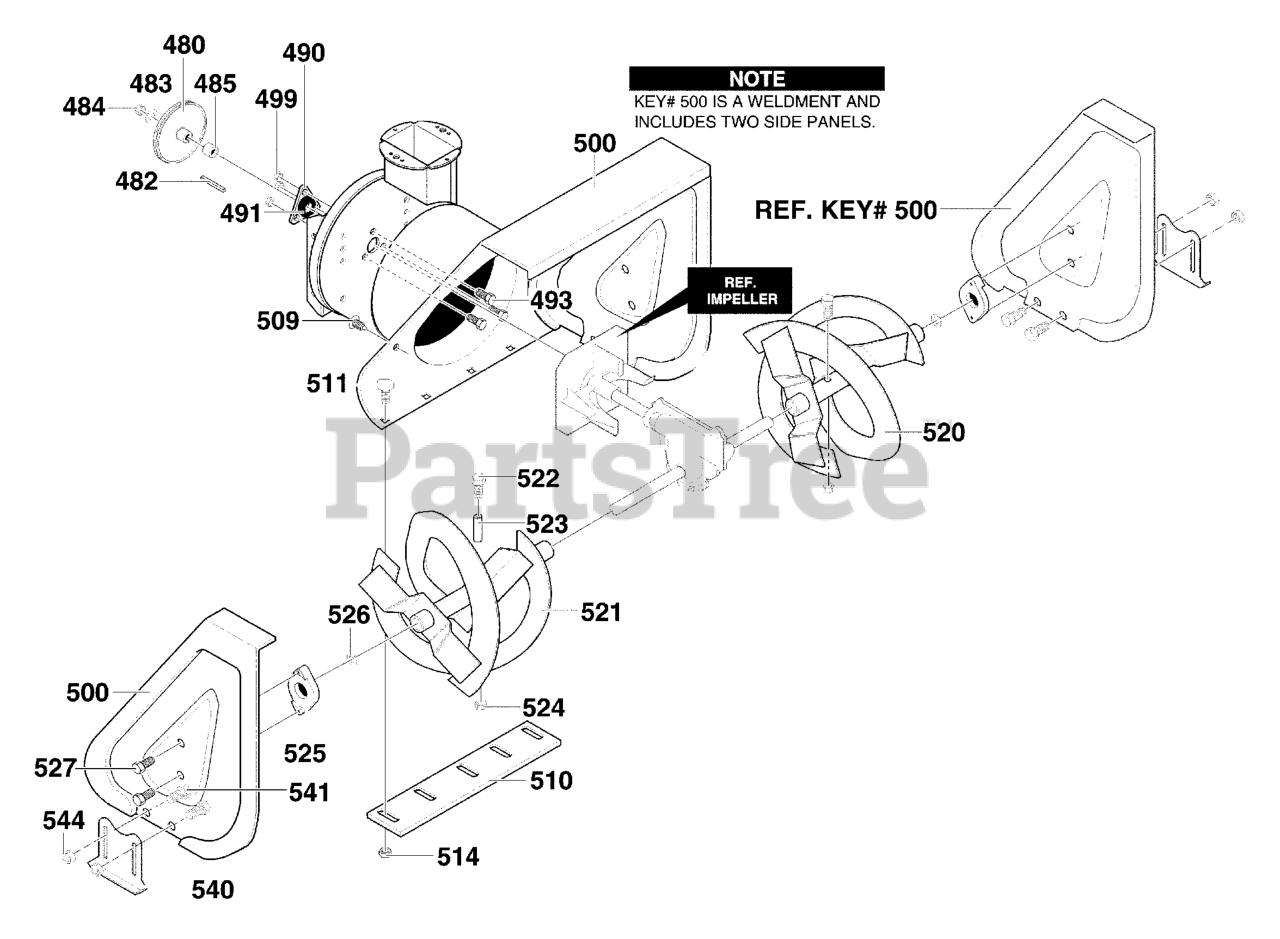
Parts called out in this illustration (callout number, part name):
482	KEY, SQUARE
483	FLATWASHER
484	NUT, 1/4-20
485	SPACER, FRICTION PULLEY
490	RETAINER, BALL BRNG
491	BEARING, BALL
493	BOLT, HEX - 0.31-18X0.50
499	NUT, 5/16-18 HEXWDFLLK
500	HOUSING, ASSY
509	PLUG, CHRISTMAS TREE
510	BLADE, SCRAPER
511	BOLT, 1/4-20X.75
520	AUGER, ASSY, LH
521	AUGER, ASSY, RH
522	SCREW, 1/4-20X1.75
523	SPACER, SLEEVE
524	NUT, 1/4-20
525	BEARING,FLANGE
527	SCREW, 5/16-18 x 0.75
540	SKID, HEIGHT ADJUST
541	BOLT, 5/16-18 X .75
544	NUT, 5/16-18 REGHEX
